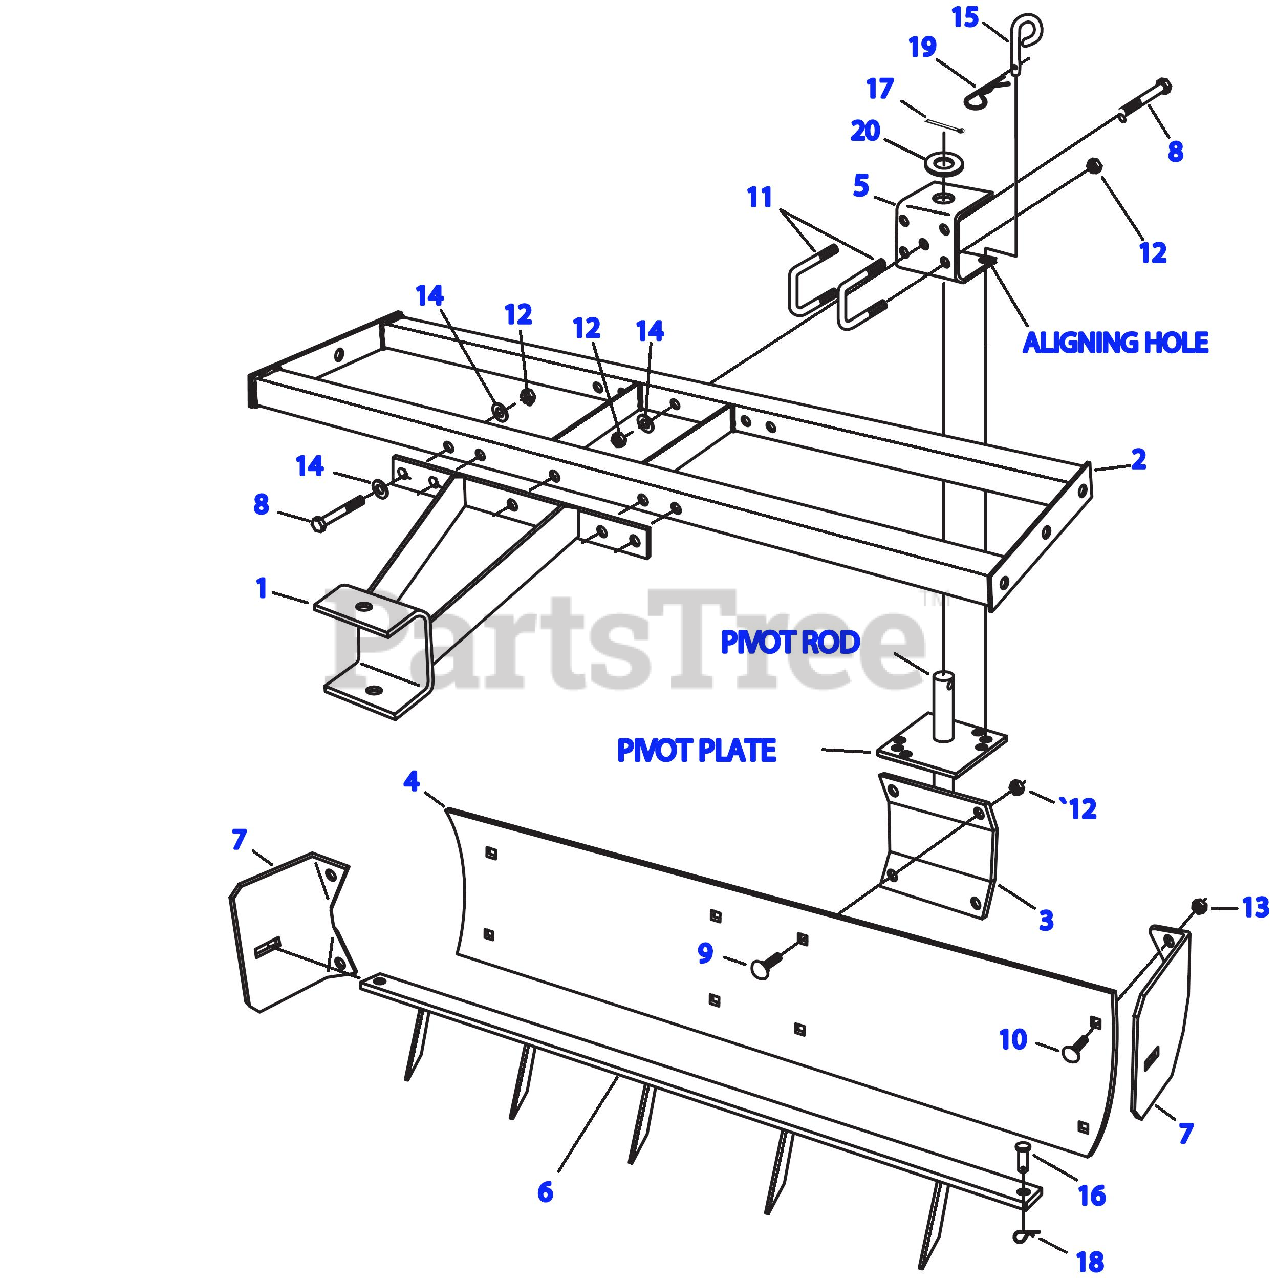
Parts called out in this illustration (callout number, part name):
1	Hitch Assembly
2	Frame Assembly
3	Pivot Bracket Assembly
5	Clevis Bracket
6	Scarifier Assembly
7	Box End Plate
8	Hex Bolt 3/8-16 X 2-1/2
10	Carriage Bolt 5/16-18 X 1
11	U Bolt 3/8-16
12	Hex Nut Ins L-3/8-16
13	Hex Nut Ins
14	Flat Washer 3/8 Id
15	Pin-Pivot Lock
16	Clevis Pin 3/8Diax.75Lg
17	Cotter Pin 3/16 X 2
18	Pin-Quick Attach
19	Hairpin Cotter 1/8
20	Special Washer
